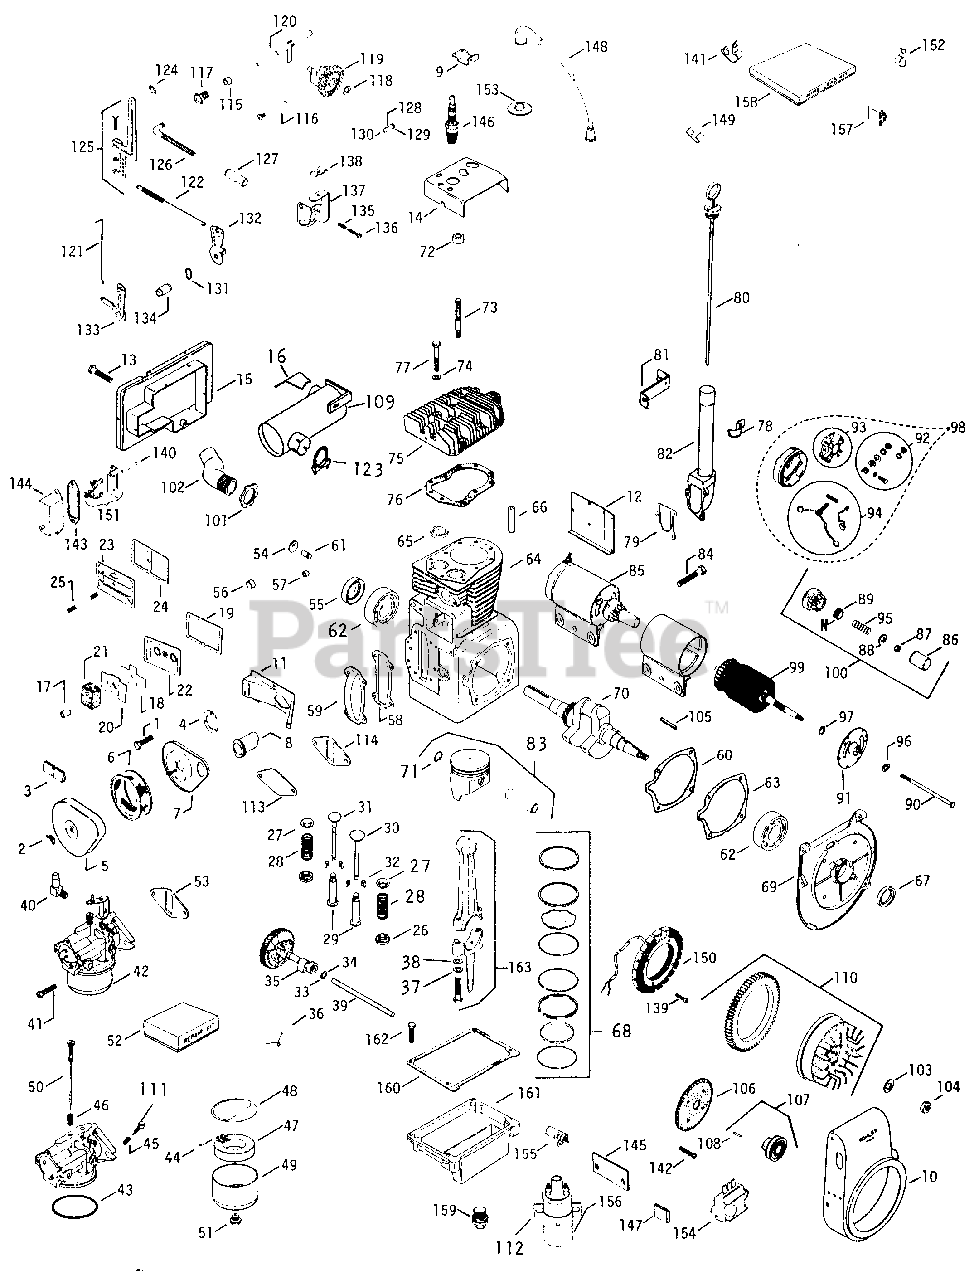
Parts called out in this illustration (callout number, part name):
1	Screw, 10-32 X 1/2 Znd Hex Hd Self Tap
2	Nut, Wing
4	Gasket, Air Cleaner
5	Cover, Air Cleaner
6	Element, Air Cleaner
7	Base, Air Cleaner
8	Tube, Air Cleaner
9	Bracket, Lifting
10	Housing, Blower
11	Baffle, Side
12	Baffle, Cylinder
13	Screw, 1/4-20 X 3/4 Hex Hd
14	Baffle, Head
16	Deflector, Exhaust
17	Seal, Breather
18	Reed, Breather
19	Gasket, Cover
20	Baffle, Breather
21	Filter, Breather
22	Plate, Breather
23	Cover, Breather
24	Gasket, Valve Cover
25	Stud, Valve Cover
26	Rotator, Valve
27	Retainer, Valve Spring
28	Spring, Valve
29	Tappet Assy
30	Valve, Intake
31	Valve, Exhaust
32	Keeper, Valve Spring
33	Shim, Camshaft, .005
34	Shim, Camshaft, .010
35	Camshaft Assy
36	Spring, Camshaft Actuating
37	Washer, 3/8 Heavy Lock
38	Washer, Connecting Rod
39	Pin, Camshaft
40	Elbow, Hose Connector
41	Screw, 5/16-18 X 1 Hex Hd Sems
42	Carburetor Assy
43	Gasket, Fuel Bowl
44	Pin, Hinge
45	Spring, Idle Adjusting Screw
46	Spring, High Speed Needle
47	Float & Lever Assy
48	Gasket, Bowl Baffle
49	Bowl, Fuel
50	Needle, High Speed
51	Screw w/Gasket, Fuel Bowl
52	Kit, Carburetor Repair
53	Gasket, Carburetor
54	Plug, 1-1/8 Expansion
55	Seal, Rear Oil
56	Plug, 1/2 Cup
57	Bearing, Crankcase Needle
58	Gasket, Cam Cover
59	Cover, Cam
60	Gasket, Bearing Plate, .010
61	Shaft, Governor
62	Bearing, Crankcase Ball
63	Gasket, Bearing Plate
64	Block, Cylinder
65	Insert, Valve Seat
66	Guide, Valve
67	Seal, Front Oil
68	Ring Set, Piston, Std
69	Plate, Bearing
71	Retainer, Piston Pin
72	Spacer
73	Stud, Cylinder Head
74	Washer, Head
75	Head, Cylinder
76	Gasket, Cylinder Head
77	Screw, 3/8-16 X 1-1/2 Znd Hex Hd Cap Type 8
78	Clamp, Conduit
79	Gasket, Oil Fill Tube
81	Bracket, Dipstick Tube
82	Tube Assy, Oil Fill
83	Piston Assy, Std
84	Bolt, Shoulder
85	Starter Assy
86	Cover, Dust
87	Nut, 5/16-24 Hex Lock
88	Spacer, Stop Gear
89	Spacer
91	Cap Assy, Drive End
92	Kit, Hardware
93	Kit, Brush Holder
94	Kit, Starter Brush
95	Spring, Anti-Drift
96	Washer, 1/4 Znd Reg Lock
97	Washer, Armature Thrust
98	Cap Assy, Commutator End
100	Kit, Starter Drive w/Shim
101	Nut, Lock
102	Elbow, Exhaust
104	Nut, 5/8-18 Znd Hex Lock
105	Key, 3/16 X 1-3/8 Sq Parallel
106	Screen, Grass
107	Cup Assy, Flywheel Drive
108	Pin, Flywheel Drive Cup
109	Muffler Assy
110	Flywheel Assy
111	Screw, Idle Adjusting
112	Clamp, Ignition Coil
113	Cover, Pad
114	Gasket, Pump Cover
115	Spacer
116	Pin, Governor Stop
117	Bushing, Governor
118	Washer, Thrust
119	Gear, Governor
120	Shaft, Governor
121	Linkage, Choke
122	Spring, Governor
123	Clamp Assy, Muffler
124	Retainer, Throttle Rod
125	Lever, Governor
126	Rod, Ball Joint
127	Body, Ball Joint
128	Clamp, Swivel Wire
129	Washer, 9/32 X 5/8 X .062 Znd
130	Screw, 1/4-20 X 1-1/4 Hex Hd Sems
131	Washer, Tension
132	Lever, Throttle Control
133	Lever, Choke Control
135	Spring, Adjusting
136	Screw, Throttle
137	Bracket, Control
138	Clamp, Wire
139	Screw, 10-24 X 3/8 Fil Hd Mach
140	Rod, Breaker
141	Clip, High Tension
142	Screw, 10-24 X 1 Znd Pan Hd Mach
143	Gasket, Breaker Cover
144	Cover, Breaker
145	Bar, Coil Bracket Back Plate
146	Plug, Spark (Champion)
147	Connector
148	Kit, Hi-Tension Lead
149	Clip, Terminal
150	Kit, Stator
151	Breaker & Bracket Assy
152	Clip, Cable
153	Grommet, Spark Plug
154	Regulator Assy
155	Condenser, Ignition Coil
156	Coil, Ignition
158	Kit, Wire Lead Cable
159	Plug, Drain
160	Gasket, Oil Pan Base
161	Base, Oil Pan
162	Screw w/Lock Washer, 3/8-16 X 1-1/2 Znd Hex Hd
163	Rod Assy, Connecting, Std
